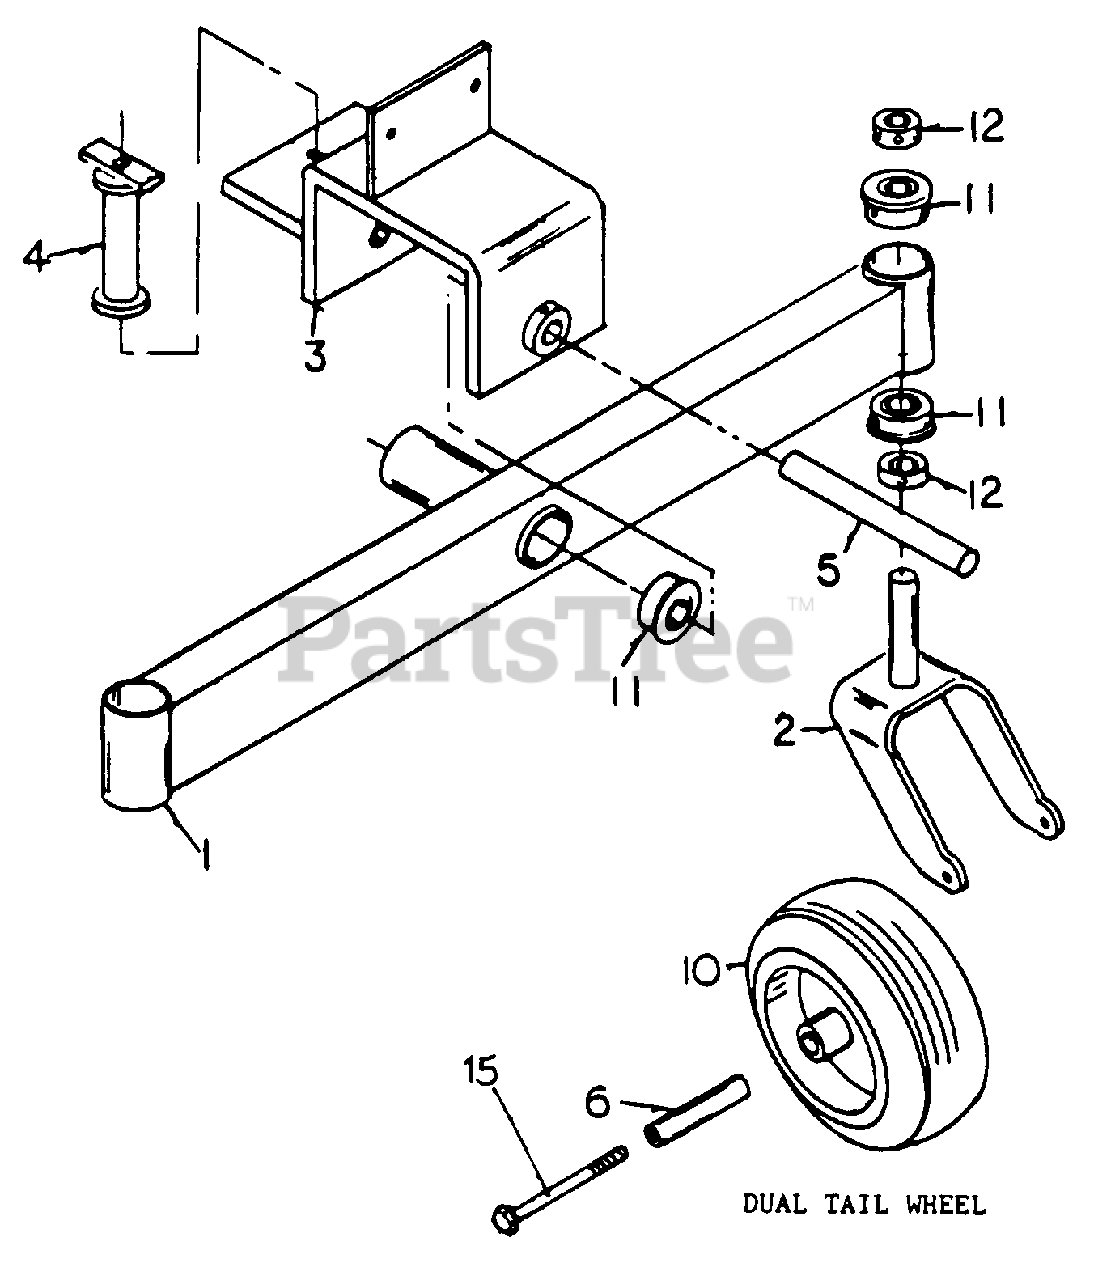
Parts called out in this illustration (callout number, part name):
1	Dual Tail Wheel Axle
2	Dual Tail Wheel Fork
3	Dual Tail Wheel Moune
4	Dual Tail Wheel Tube Block
6	Tail Wheel Axle
10	Tail Wheel Assembly
12	Set Collar, 1"
15	Hex Capscrew, 1/2-13 x 6 1/2"
